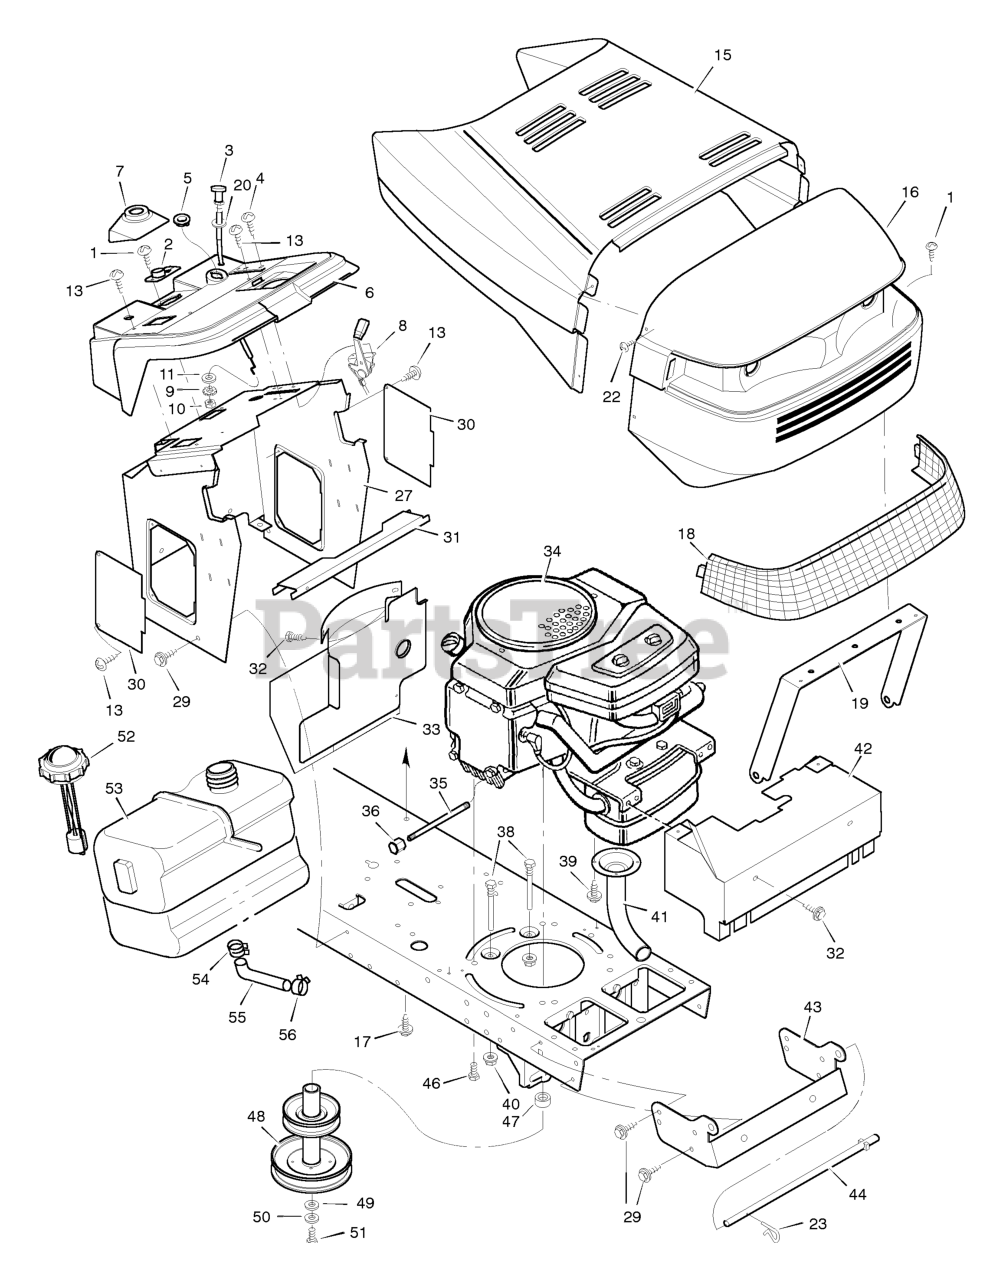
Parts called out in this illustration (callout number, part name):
2	Bearing, Steering Post
3	Cable, Choke
5	Bushing
7	Support, Bellows
8	Throttle Control
9	Lockwasher
10	Nut, Hex
13	Screw
15	Hood
16	Grille
19	Brace, Grille
20	Washer
23	Pin, Hair
27	Console Assembly
30	Panel, Side Access
31	Support, Fuel Tank
32	Screw
33	Baffle, Rear Heat
34	Engine *
35	Oil Drain Extension
36	Oil Drain Cap
38	Guide, Belt
40	Locknut, Flange
41	Pipe, Exhaust
42	Shield, Heat
43	Support, Grille
44	Rod, Pivot
46	Bolt, Hex
47	Spacer, Engine
48	Pulley Assembly, Stack
50	Lockwasher
51	Bolt, Hex
52	Cap, Fuel
53	Fuel Tank
54	Clamp, Hose
55	Fuel Line
56	Clamp, Hose
